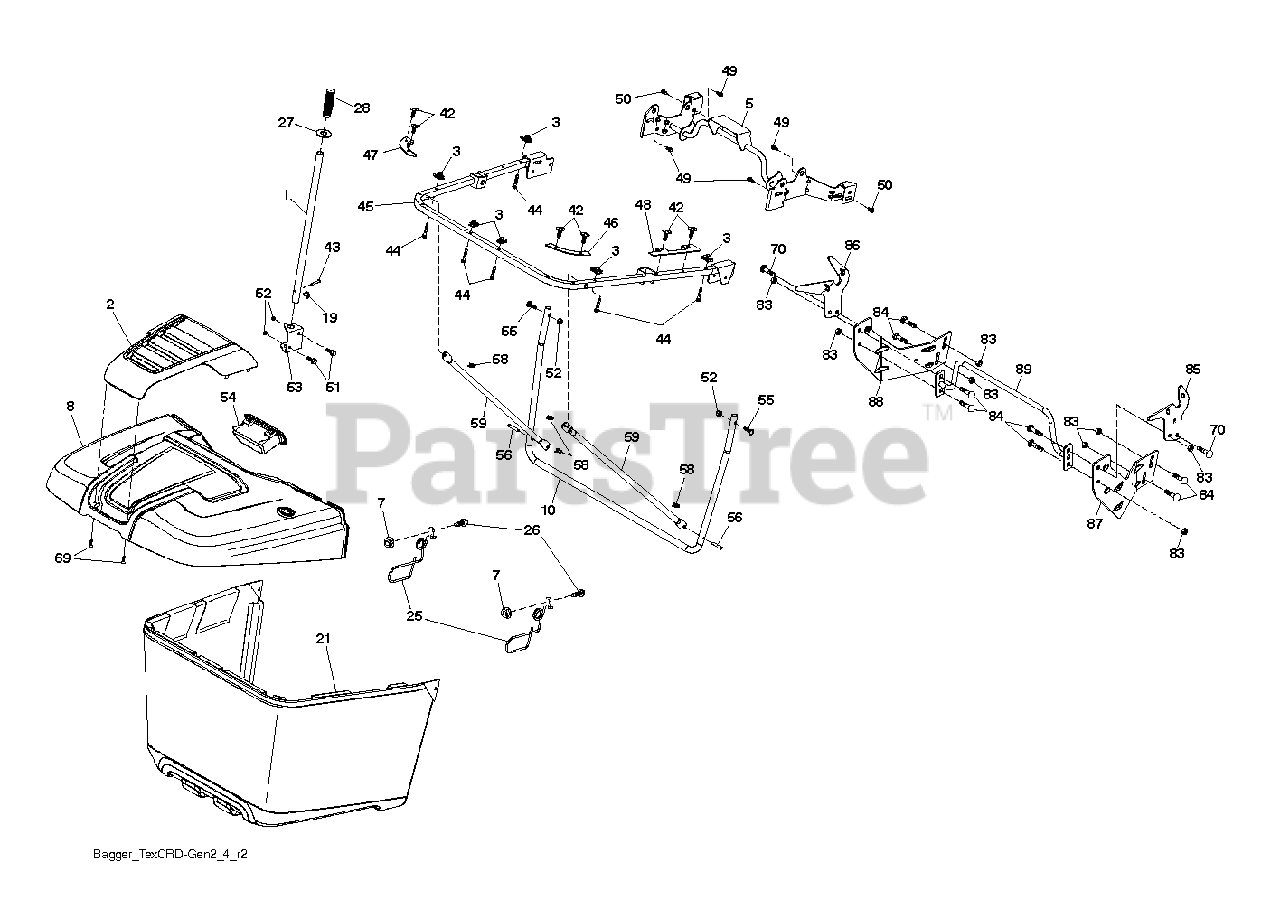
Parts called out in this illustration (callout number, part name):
1	TUBE.HANDLE.BAGGER.CRD/SRD.BLA
2	APPLIQUE.BAGGER
3	1/4-20 U NUT
5	FRAME TEX_CRD_GEN2 UPPER PIVOT
7	NUT T
8	BAGGER TOP
10	FRAME TEX_CRD_GEN2 BAGGER FRAM
19	PIN.COTTER.5/16.BOW TI
21	BAG FRAME BAGGER ASSEMBLY. HUS
25	LATCH LATCH. BAG. CRD GEN 2
26	SCREW HEX CRT
27	GROMMET RUBBER GROMMET, DUMP T
28	GRIP.HANDLE.BLACK
42	CLIP CHRISTMAS TREE CLIP
43	RIVET,DRILLED
45	FRAME TEX_CRD_GEN2 UPPER U FRA
46	CONNECTOR RIGHT BAGGER CORNER
47	CONNECTOR LEFT BAGGER CORNER C
48	BAFFLE BAGGER SIDE CLOSE-OUT
49	BOLT, SHOULDER 5/16-18
50	BOLT, 5/16-18 X 1 3/4
51	BOLT.CARR.SQNK.5/16-18UNC.X3/4
52	NUT.71038.31-18.HEX.NYLOCK
53	BRACKET DUMP HANDLE BRACKET, T
54	HANDLE BAGGER TOP FRONT HANDLE
55	BOLT
56	PIN.CLEVIS.183
58	RETAINER CLIP PM
59	TUBE BAGGER SPREADER TUBE, TEX
69	SCREW,#8.FLAT.HEAD.DRILL.TIP
70	SCREW, 3/8-16X3/4
83	NUT
84	BOLT D
85	BRACKET.RH.PIVOT.MAN.DUMP.BLAC
86	BRACKET.LH.PIVOT.MAN.DUMP.BLAC
87	BRACKET.RH.MID.SUP.BAG.TEX.CRD
88	BRACKET.LH.MID.SUP.BAG.TEX.CRD
89	TUBE.WELD.OFSET.STRUT.BAG.X431
